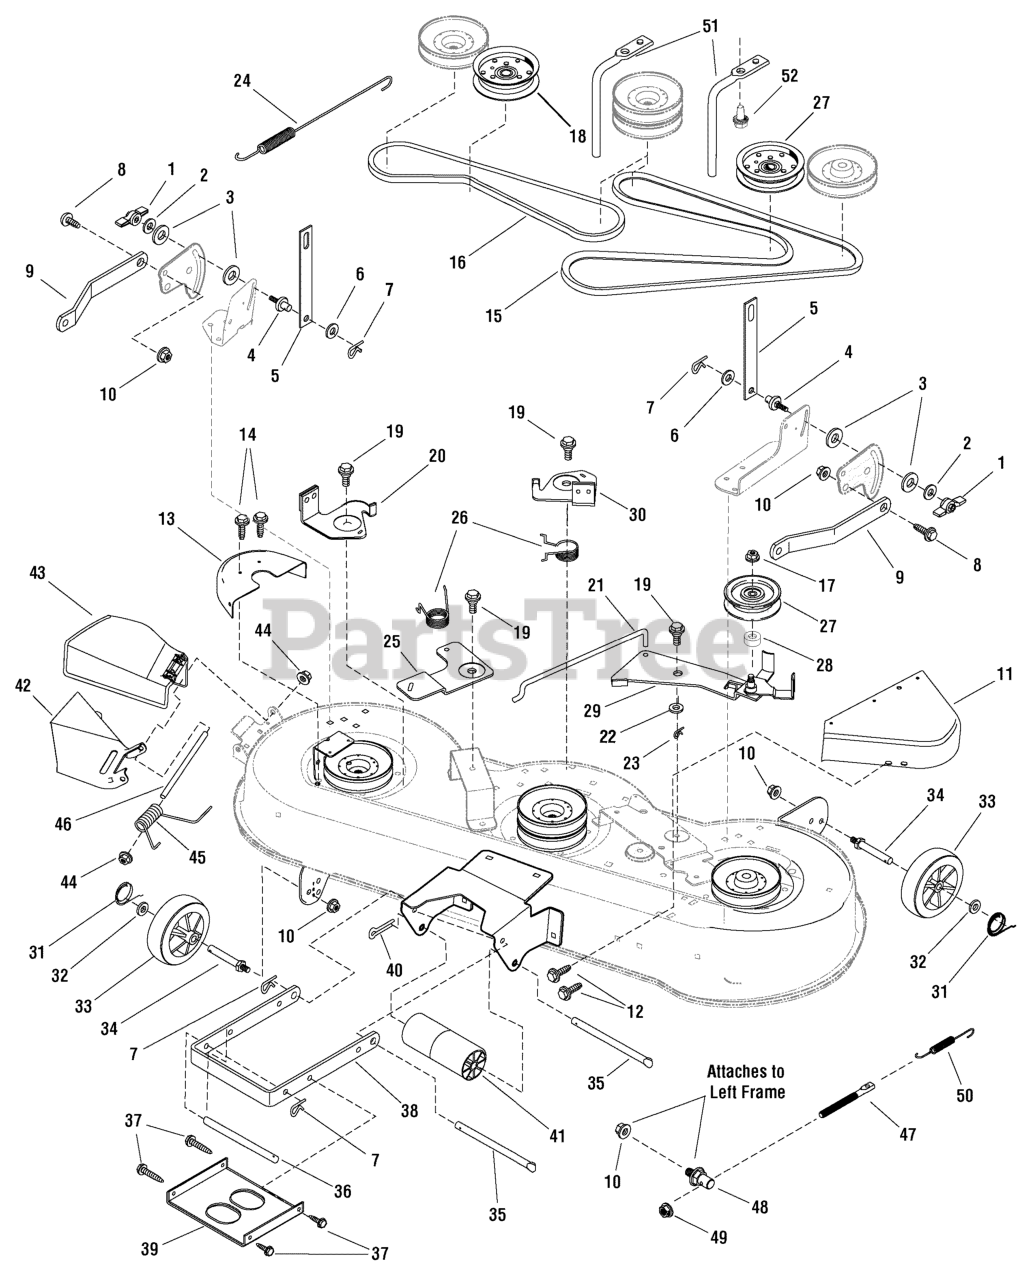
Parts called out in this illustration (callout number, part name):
1	KNOB, (5/16-18 thread)
2	WASHER, FLAT, 1.0 X .328 X 16GA
3	FRICTION PAD
4	PIN, Hanger 3/8-16 x 1-1/4
5	LINK, Lift
6	WASHER, Flat 1
7	PIN, Hair
8	BOLT, Shoulder 3/8-16 x 1
9	BRACKET, Rear Suspension
10	NUT, Hex Flange, 3/8-16
11	COVER, Left Pulley
12	SCREW, 5/16-18 x 1/2
13	COVER, Right Pulley
14	SCREW, Hex Washer Head Taptite
15	BELT, Primary 46 in
16	BELT, Secondary, 46 in
17	NUT, Flange, 3/8-16
18	PULLEY, Idler, Right
19	BOLT, Shoulder 3/8-16 x 3/5
20	BRAKE ASSEMBLY, Center
21	LINK, Bellcrank
22	Washer, Flat 5/8"
23	PIN, Cotter, 3/4
26	SPRING, Torsion Brake
27	PULLEY, Idler, Left
28	SPACER, 1/2" TO 17mm
29	IDLER ARM, 46 in, Left
30	BRAKE ASSEMBLY, Left
31	CLIP, Hair Pin
32	WASHER, Flat, 7/8
33	WHEEL GAGE
34	BOLT, Gauge Wheel
35	ROD, Deck Suspension
36	ROD, Hanger
37	CAPSCREW, 5/16-18
38	BRACKET, Front Suspension
40	COTTER PIN
42	DEFLECTOR, Inside
43	DEFLECTOR, Chute
44	CAP, Push On
45	SPRING, Torsion
46	ROD, Deflector
47	STUD, Spring Mounting
48	STUD, Swivel (3/8-16 thread)
49	NUT, Hex Flange Lock, 5/16-18
50	Spring, Extension
51	Guide, Belt
52	SCREW, 3/8-16 x 3/4
